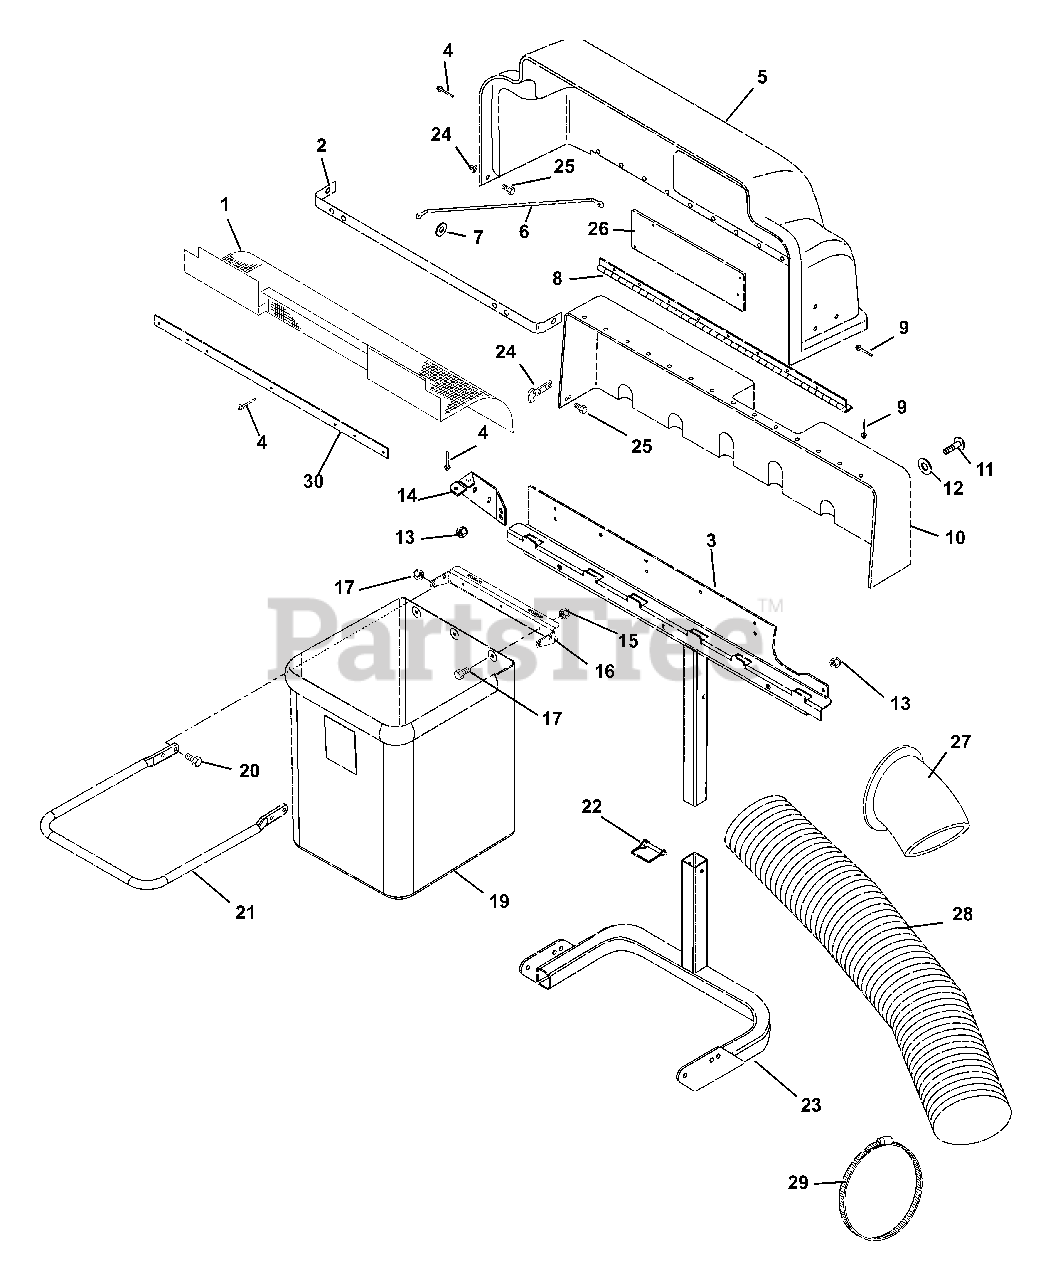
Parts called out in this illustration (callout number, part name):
2	SCREEN MOUNTING BRACKET
3	WELDMENT-BAGGER FRAME
4	RVT-POP.187X.527 DOME ST
5	HINGED COVER W/DECAL
6	BRACE
7	@WSHR-FL-STL .188X.438X.049 YZ
8	HINGE- 2.0"X35.0"
9	RVT-POP .187X.402 DOME ST
10	STATIONARY COVER
11	@BLT-HEX .31-18X.75 GR5 YWZC
12	@WSHR-FL-STL.38X.875X.083 YWZC
13	@NUT-LK-CTR .31-18 YWZC
14	BRACE
15	@NUT-LK-CTR .25-20 YWZC
16	WMT, HANGER FRAME
17	@BLT-HEX .25-20X.50 GR5 YWZC
18	@NUT-SPNLK-FLG .312-18 YWZC
19	BAG-MESH ASSIST BAGGER
20	@BLT-RHDSSQNK .31-18X.75 G5YZ
21	FRAME-BAG SUPPORT
22	PIN-3/8 X 2.50 SQ LOCK
23	WELDMENT-BUMPER & BAG HOLDER
24	LATCH, RUBBER
25	@SCR-MCH 10-24X.50 HWH YWZC
27	BAGGER BOOT - UPPER
28	HOSE 7 X 45
29	CLAMP-HOSE WRM 2.13/8.62X.56
30	GUARD - SCREEN
